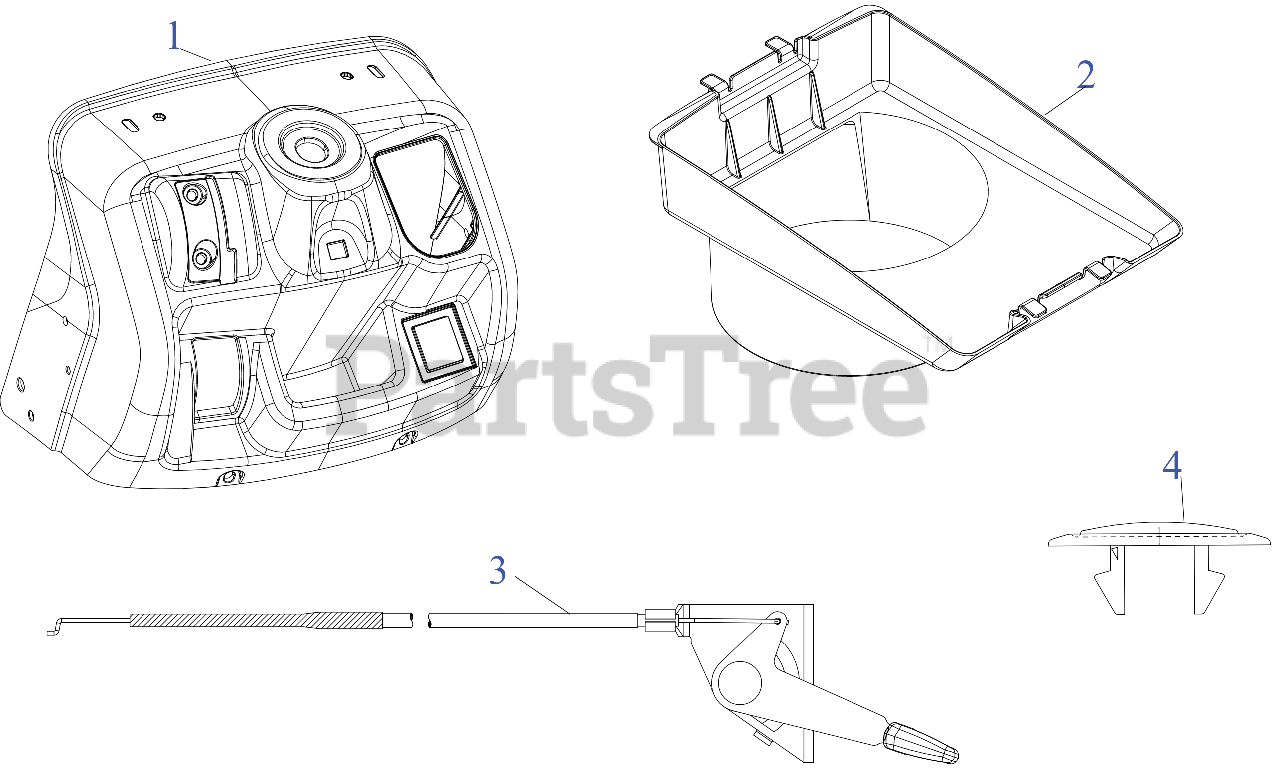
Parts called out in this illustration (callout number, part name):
1	UPPER DASH
2	HOOD PLENUM
3	THROTTLE CABLE 31" x 1.1
4	CHOKE PLUG
